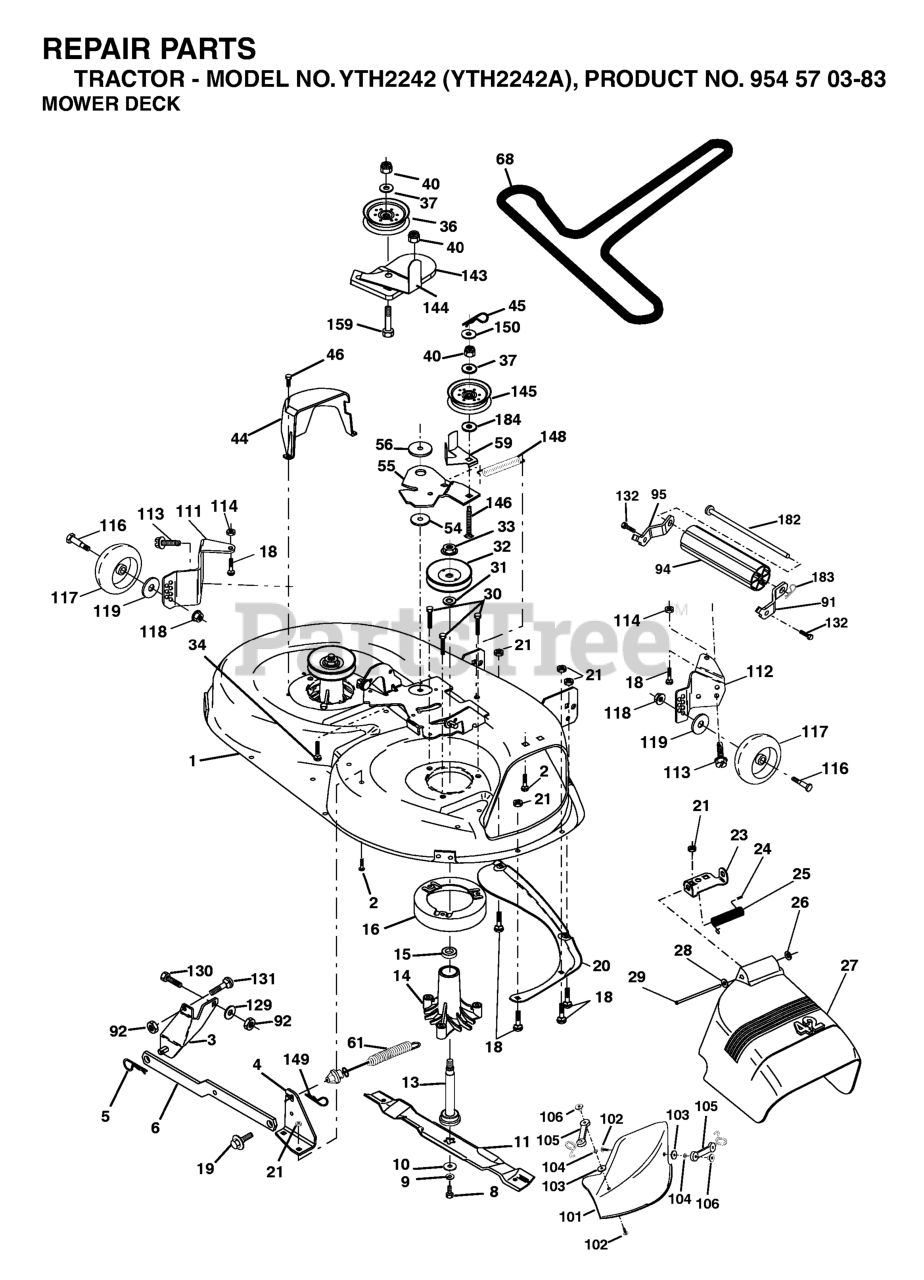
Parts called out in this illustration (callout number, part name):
1	DECK SVC 42"
2	RP BOLT 5/16-18 X3/4 ZN/YEL GR
3	BRKT ASM SWAY BAR
4	BRACKET SWAY BAR 42" DECK
5	RETAINER-SPRNG RB
6	BAR SWAY DECK
8	BLADE BOLT
9	LOCKWASHER
10	WASHER.BLADE
11	BLADE.42".MULCH
13	SHAFT ASM VENT
14	HOUSING.MANDREL.VENTED (MACHD)
16	STRIPPER.MANDREL.ROUND.BLACK
18	BOLT
19	BOLT SHD 5/16-18
20	BAFFLE.VORTEX
21	LOCKNUT
22	STIFFENER BRACKET
23	BRKT, DEFL. MOWER
24	CAP-SLEEVE LT
25	SPRING TORSION
26	NUT PUSH M
27	SHIELD DEFLECTOR
28	Washer 11/32 x 5/8 x 16 Ga SD
29	ROD.HINGE
30	SCREW, WASHER HEAD
31	WASHER
32	PULLEY MANDREL
33	NUT, FLG TOPLOCK 9/16"
36	PULLEY.IDLER.FLAT
37	WASHER
44	GUARD MANDREL LH BLACK
45	RETAINER M
46	SCREW.1/4-20X5/8
55	ARM IDLER 42" MOWER LT/YT
56	SPACER RETAINER
59	GUARD TUV IDLER
61	SPRING EXT ELEC CLUTCH
68	V-BELT PRIMARY 42"
91	BRACKET ASM NOSEROLLER LH
92	NUT.71038.31-18.HEX.NYLOCK
94	NOSE ROLLER
95	BRACKET ASM NOSEROLLER RH
101	COVER MULCH 42"
102	SCREW
104	LOCKWASHER #10
105	LATCH ASSY
106	WELDNUT
111	GUAGE WHEEL BRACKET LH
112	BRACKET WHEEL GUAGE KIT
113	Screw Tapping 3/8-16 x .625
114	NUT
116	BOLT M
117	WHEEL.GAUGE.STANDARD
118	LOCKNUT
119	WASHER.5/16.FLAT.STE.STD.
129	WASHER
131	BOLT D
132	SCREW, 3/8-16X3/4
143	BRACKET, ARM IDLER
144	KEEPER BELT 42" CLUTCH
145	PULLEY.IDLER.FLAT.PLATED
146	BOLT CARRIAGE IDLER
148	IDLER RETURN SPRING
149	SPRING.RETAINER.YELLOW.ZINC
182	ROD ROLLER NOSE STANDARD
183	SPRING RETAINER
184	WASHER
